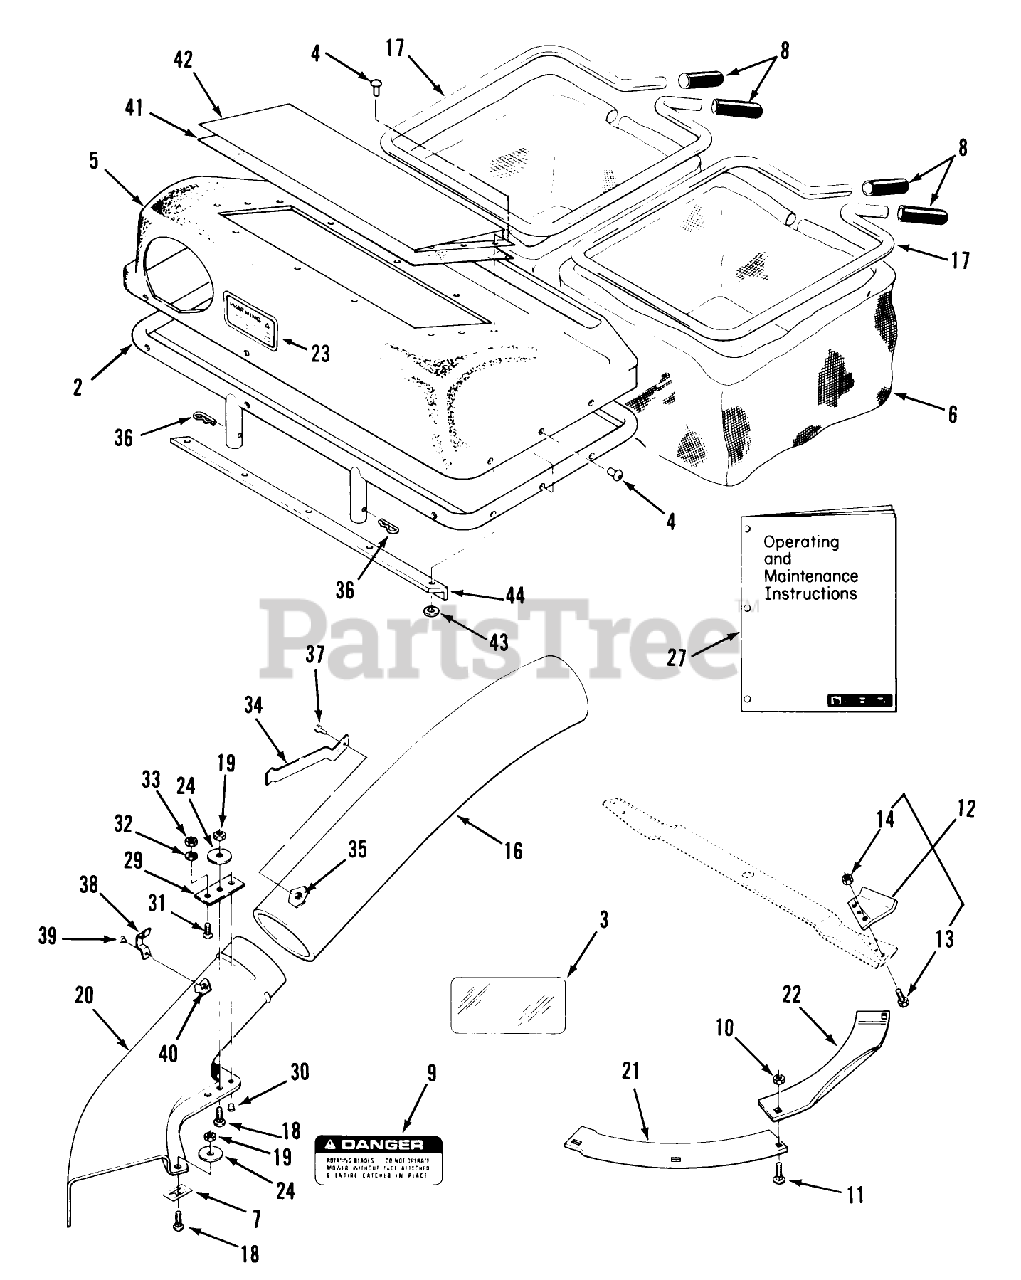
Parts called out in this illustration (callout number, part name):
3	DECAL-OVERLAY
4	RIVET-BLIND
7	SPEED NUT
8	GRIP
9	DECAL-DANGER
12	S/A LIFT TAB KIT
13	BOLT 5/16-18X5/8
14	NUT-HEX
22	PLATE MOWER *B
24	WASHER
27	Operating and Maintenance Instructions
30	RIVET -4
36	Pin-Cotter
38	BRACKET
